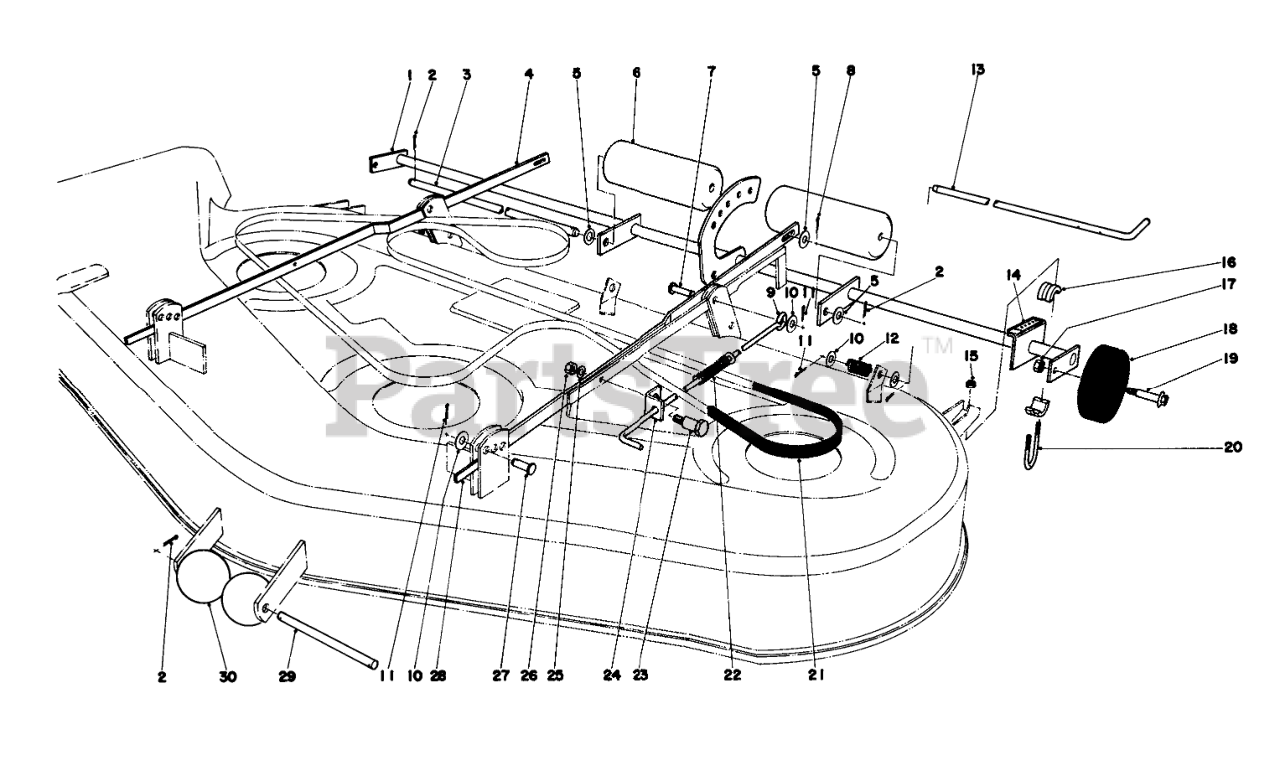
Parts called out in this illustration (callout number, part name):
1	DECK WHL SHAFT WA B
2	PIN-COTTER
3	ROLLER SHAFT B
4	RR SCISSORS LNK B
5	WASHER-FLAT
6	ROLLER-DECK
7	PIN-CLEVIS
8	PIN-COTTER
9	Pin Tension
10	WASHER-FLAT
11	PIN-COTTER
12	Spring
13	WHEEL LATCH ROD B
14	Decal-Height of Cut
15	NUT-LOCK, CONE
16	BEARING DECK SH WHEEL
17	Nut
18	DECK WHEEL
20	U-BOLT
21	V-BELT, DECK
22	COMP SPRING
23	Bolt-Shoulder
24	TENSION BELT BRKT B
25	WASHER-PLAIN
26	NUT-LOCK, CONE
27	PIN-CLEVIS
28	Scissors Link Rear L.H.
29	ROLLER SHAFT
30	ROLLER
